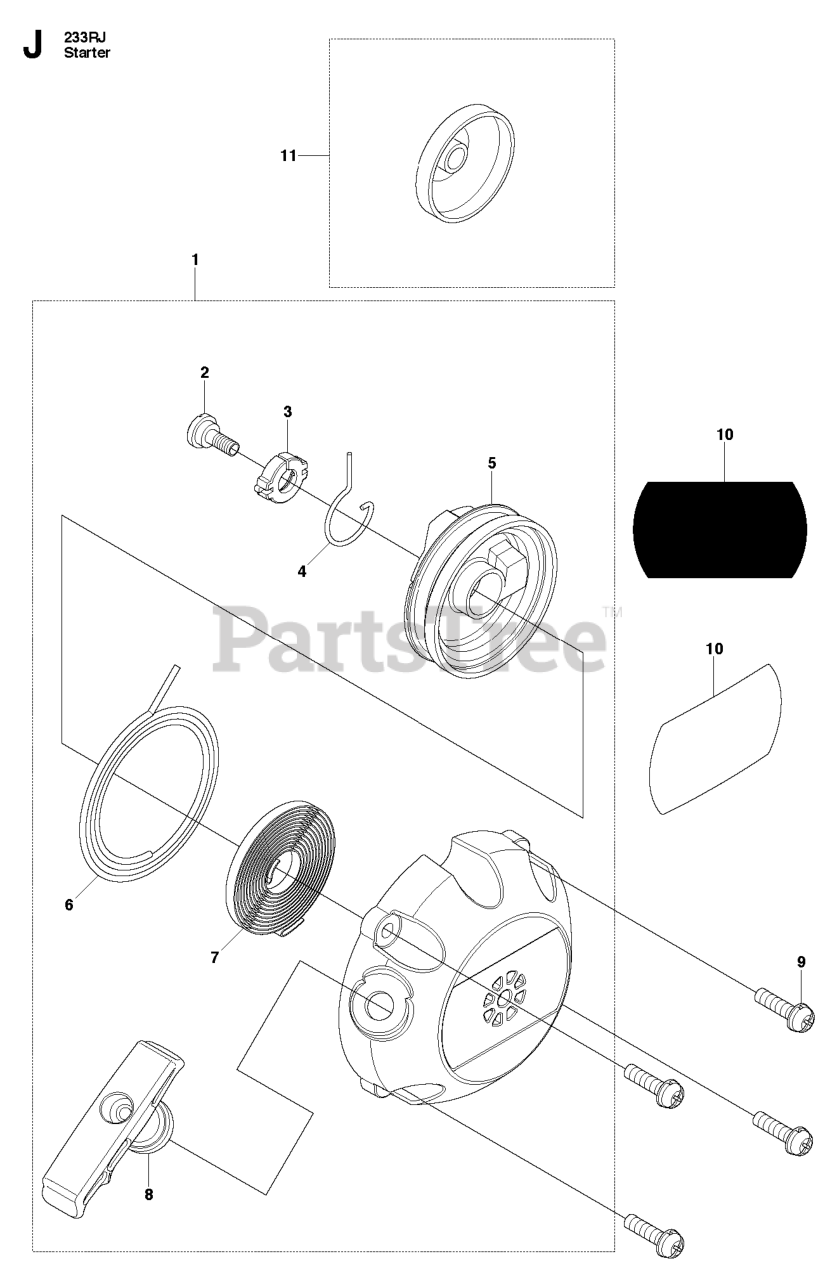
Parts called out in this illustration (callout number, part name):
6	ROPE (RPLS 450075160)
9	BOLT TORX
11	PULLEY
